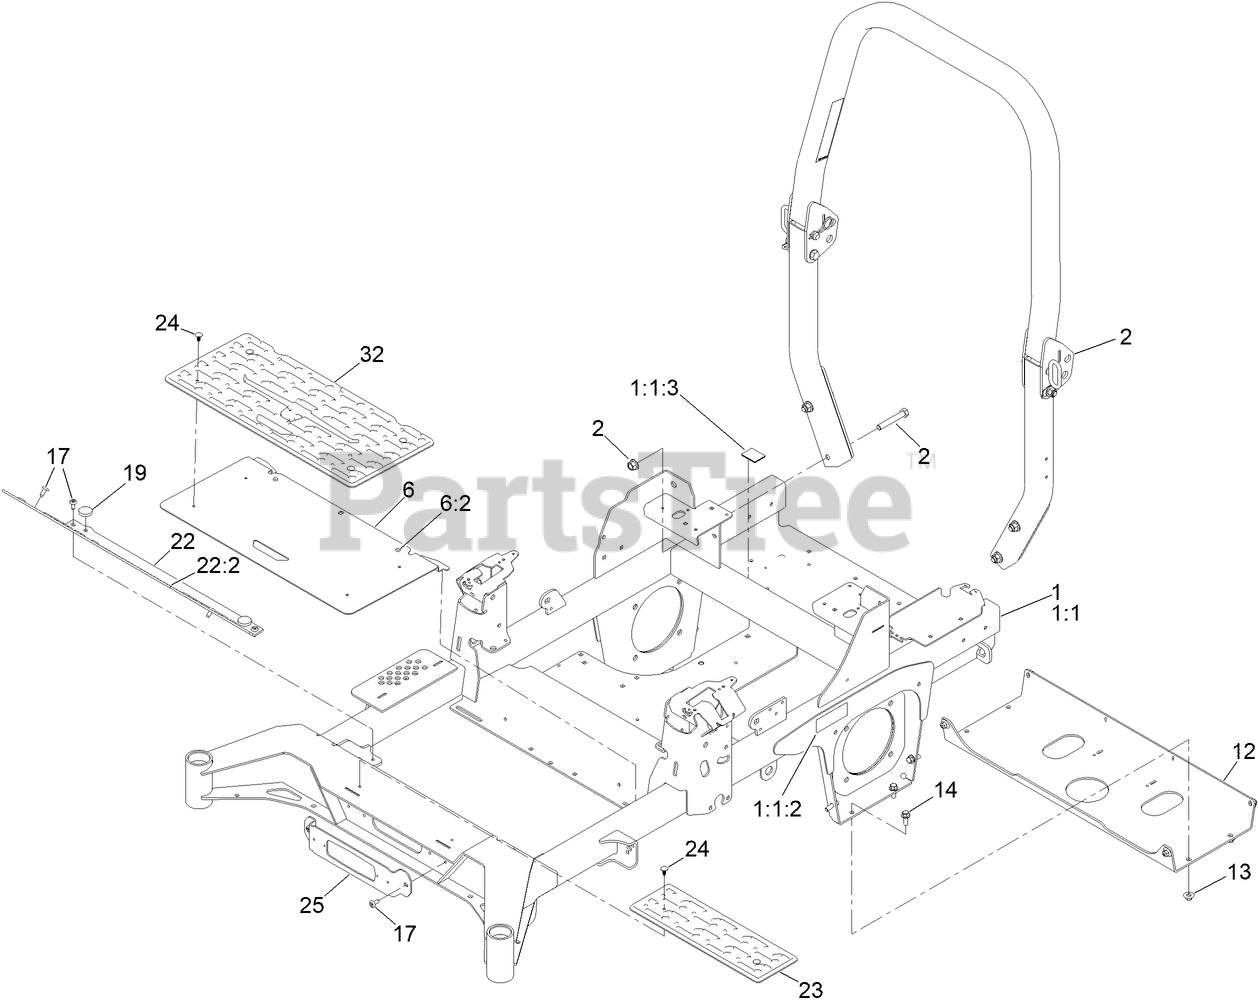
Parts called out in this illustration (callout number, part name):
1	FRAME ASM
1:1	FRAME-60 XL
1:1:2	DECAL-WARNING
1:1:3	DECAL, BELT ROUTING
2	ASM-ROPS
6	ASM-FLOOR PAN
6:2	BUMPER-PUSH-IN, RUBBER
12	PLATE-HYDRO
13	NUT-FLANGE, NI
14	SCREW-HHF
19	BUMPER-PUSH-IN, RUBBER
22	TOEBOARD
22:2	DECAL-DANGER
24	PLUG-PLASTIC
25	BRACKET-LIGHT
32	FLOORMAT-FIXED SEAT
